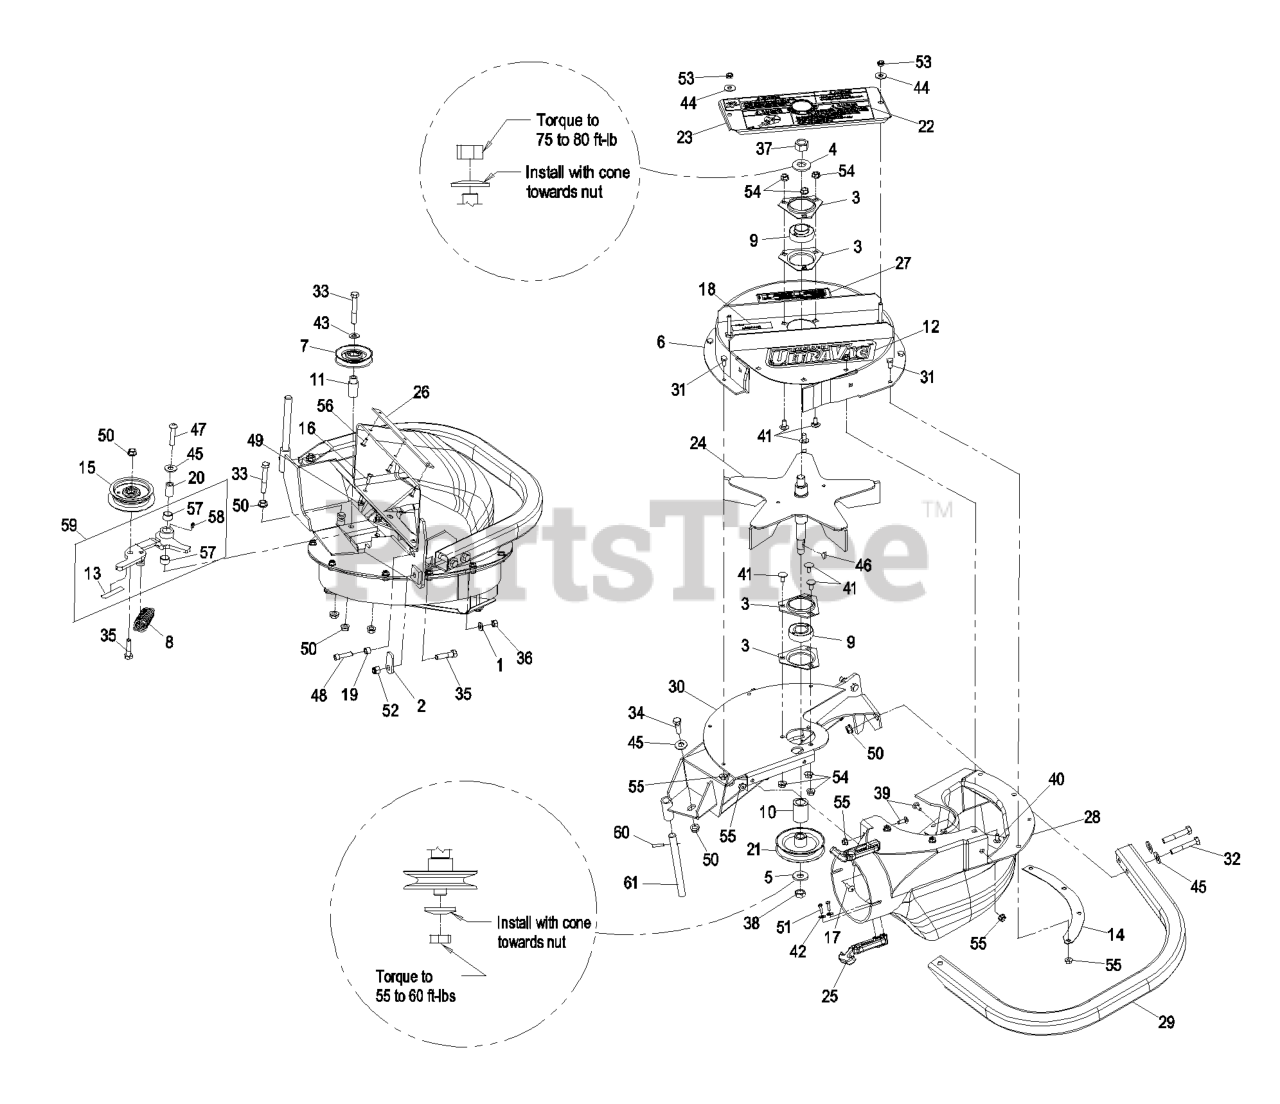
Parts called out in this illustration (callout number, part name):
1	WASHER-SPRING
2	LATCH-CATCHER, GRASS
3	HOUSING-FLANGE
4	WASHER-SPRING
5	WASHER-SPRING
6	ASM,UPPER HOUSING
7	IDLER-INSIDE
8	SPRING-IDLER
9	BEARING
12	DECAL, ULTRA VAC
13	DECAL-WARNING
14	PLATE-BACKING, BLOWER
15	IDLER-FLAT
16	SCREW-HEAD, TRUSS
18	DECAL-COVER, MISSING
19	BUSHING, LOCATOR
20	BUSHING-PIVOT, IDLER
21	SHEAVE-BLOWER
22	DECAL-WARNING
23	ASM, BEARING COVER
24	IMPELLER
25	LATCH-RUBBER
26	PLATE-REINFORCEMENT
27	DECAL,WEIGHT
28	ASM,BLOWER CHUTE LHP
30	WELD, FRAME SM BLOWER
31	SCREW-HH
32	SCREW-HH
33	BOLT-CARR
34	SCREW-HH
35	SCREW-HH
36	NUT-HEX
37	NUT-HEX
38	NUT-JAM
39	BOLT-CARR
40	SCREW-CARR
41	SCREW-CARR
42	WASHER-FLAT
43	WASHER-FLAT
44	WASHER-FLAT
45	WASHER-FLAT
46	KEY-WOODRUFF
47	SCREW-HSBH
48	SCREW-HSH
50	NUT-HHF, WHIZ
51	SCREW-PPH
52	NUT-LOCK, NI
53	NUT-LOCK, NI
56	RIVET-BLIND
57	BUSHING
58	FITTING-GREASE
59	ASM, IDLER ARM - SERVICE
60	PIN-ROLL
61	SHAFT-CATCHER, GRASS
